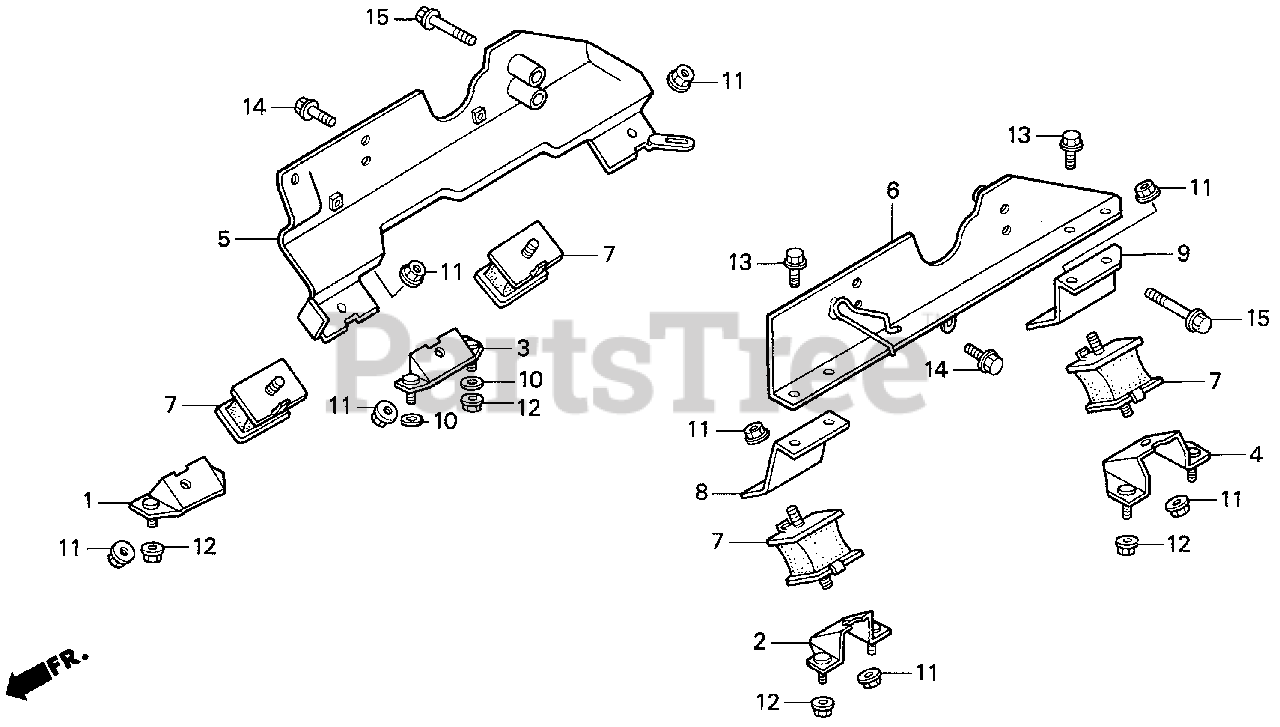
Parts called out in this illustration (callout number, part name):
1	BRACKET A, ENGINE MOUNTING
2	BRACKET B, ENGINE MOUNTING
3	BRACKET, ENGINE SETTING (C)
4	BRACKET, ENGINE MOUNTING (D)
5	BRACKET, R. ENGINE MOUNTING
6	BRACKET, L. ENGINE MOUNTING
7	RUBBER, ENGINE MOUNTING
8	SUB-BRACKET, L. FR. ENGINE SETTING
9	BRACKET, L. RR. ENGINE MOUNTING SUB
10	WASHER (8MM)
11	NUT, FLANGE (10MM)
12	NUT-WASHER (8MM)
13	BOLT, FLANGE (8X20)
14	BOLT, FLANGE (10X25)
15	BOLT, FLANGE (10X50)
